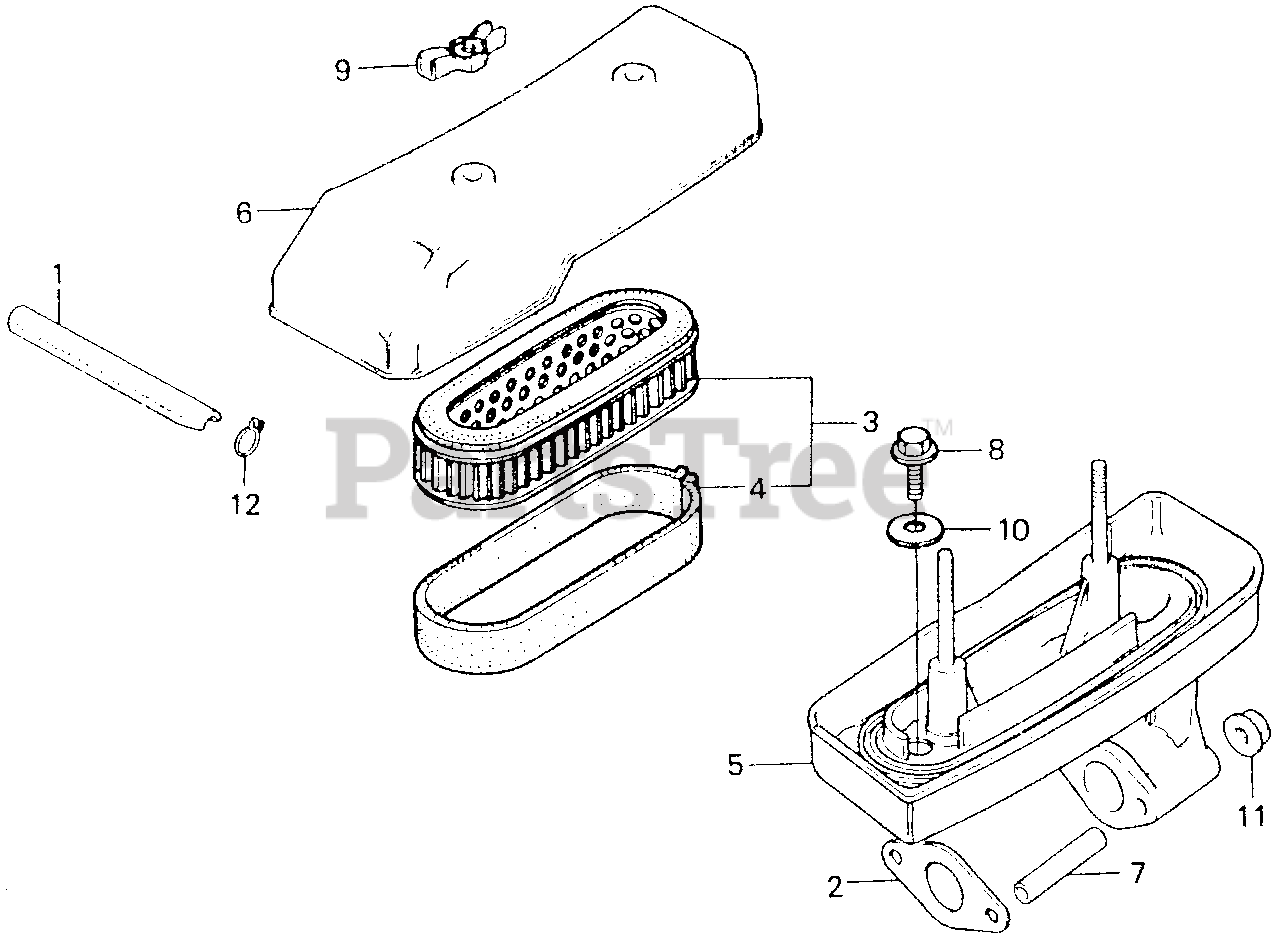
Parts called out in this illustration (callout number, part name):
1	TUBE, BREATHER (NOT AVAILABLE)
2	GASKET, AIR CLEANER
3	ELEMENT, AIR CLEANER
4	FILTER (OUTER)
5	HOUSING, AIR CLEANER (NOT AVAILABLE)
6	COVER, AIR CLEANER
7	COLLAR, AIR CLEANER HOUSING (NOT AVAILABLE)
8	BOLT, FLANGE (6X12) (CT200)
9	NUT, AIR CLEANER COVER (DACRO COATING)
10	WASHER, HEADLIGHT CASE
11	NUT, FLANGE (6MM)
12	CLIP, TUBE (B12.5)
